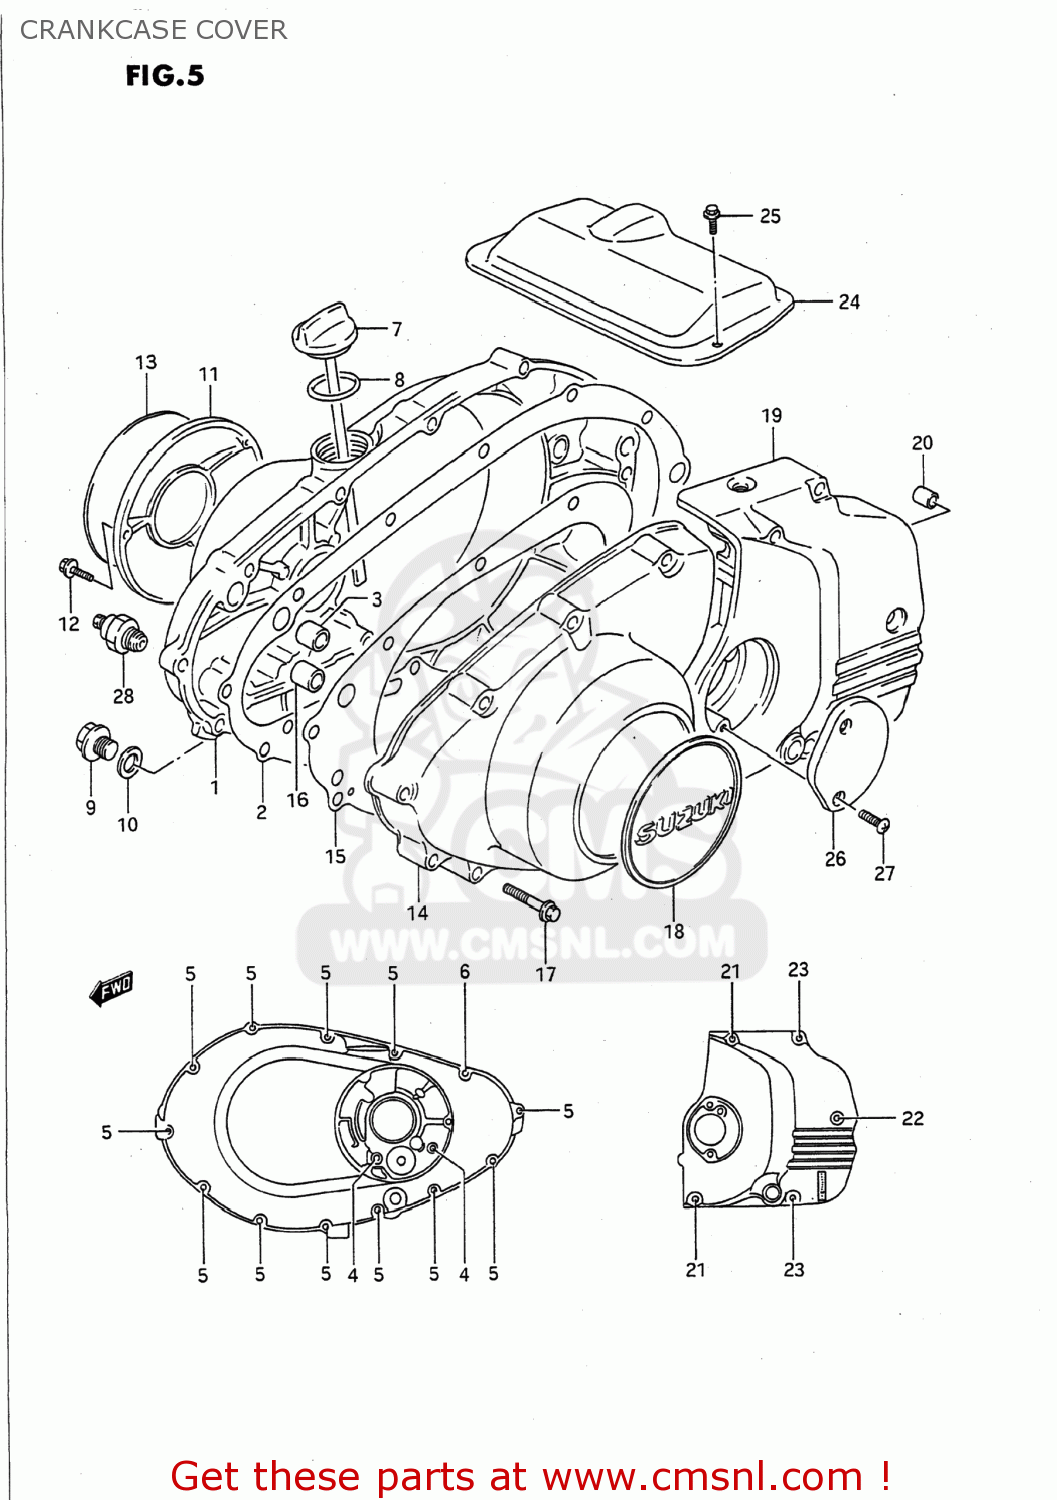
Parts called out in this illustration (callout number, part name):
1	COVER,CLUTCH
2	GASKET,CLUTCH COVER (MCA)
3	PIN
4	BOLT
5	BOLT
6	BOLT
7	GAUGE,OIL LEVEL
8	O-RING
9	PLUG(14X12)
10	GASKET(13.8X18.8X4.8) (NAS)
11	COVER,CONTACT BREAKER
12	BOLT
13	EMBLEM,CONTACT BREAKER COVER
14	COVER,MAGNETO
15	GASKET,MAGNETO COVER (NAS)
16	PIN
17	BOLT
18	EMBLEM,CONTACT BREAKER COVER
19	COVER,ENGINE SPROCKET
20	PIN
21	BOLT
22	BOLT
23	BOLT
24	COVER,STARTER MOTOR
25	BOLT
26	CAP,CLUTCH RELEASE ADJUST
27	SCREW
28	SWITCH ASSEMBLY,OIL PRESSURE
